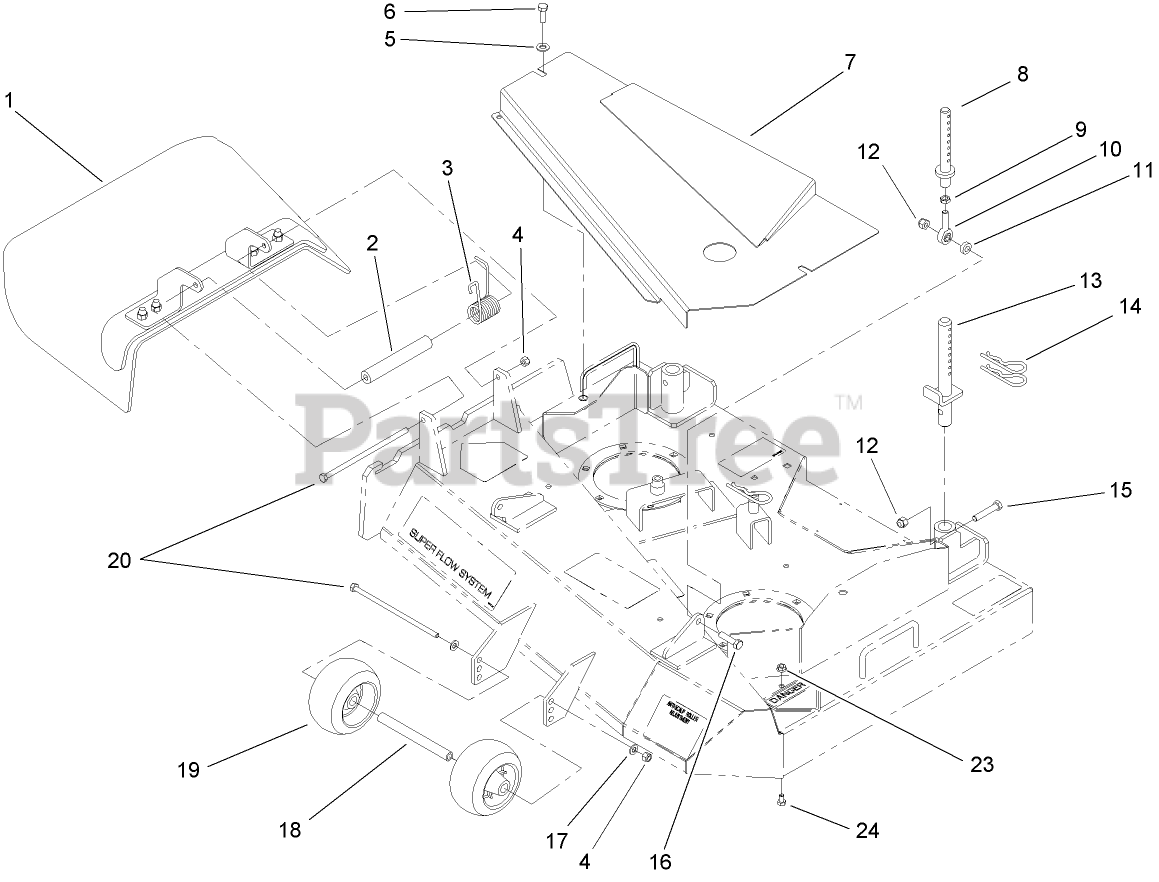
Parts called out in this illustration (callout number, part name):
1	DEFLECTOR ASM
2	SPACER
3	SPRING-TORSION
4	NUT-LOCK, NI
5	WASHER-FLAT
6	SCREW-HH
7	COVER ASM
8	FRONT PIN ASM
9	NUT-HJ
10	BALLJOINT
11	SPACER
12	NUT-LOCK, NI
13	REAR PIN ASM
14	PIN-HAIR
15	SCREW-HH
16	SCREW-HH
17	WASHER-PLAIN
18	SPACER-WHEEL
19	ROLLER-SCALP, ANTI
20	SCREW-HH
23	NUT-HF
24	SCREW-HH
